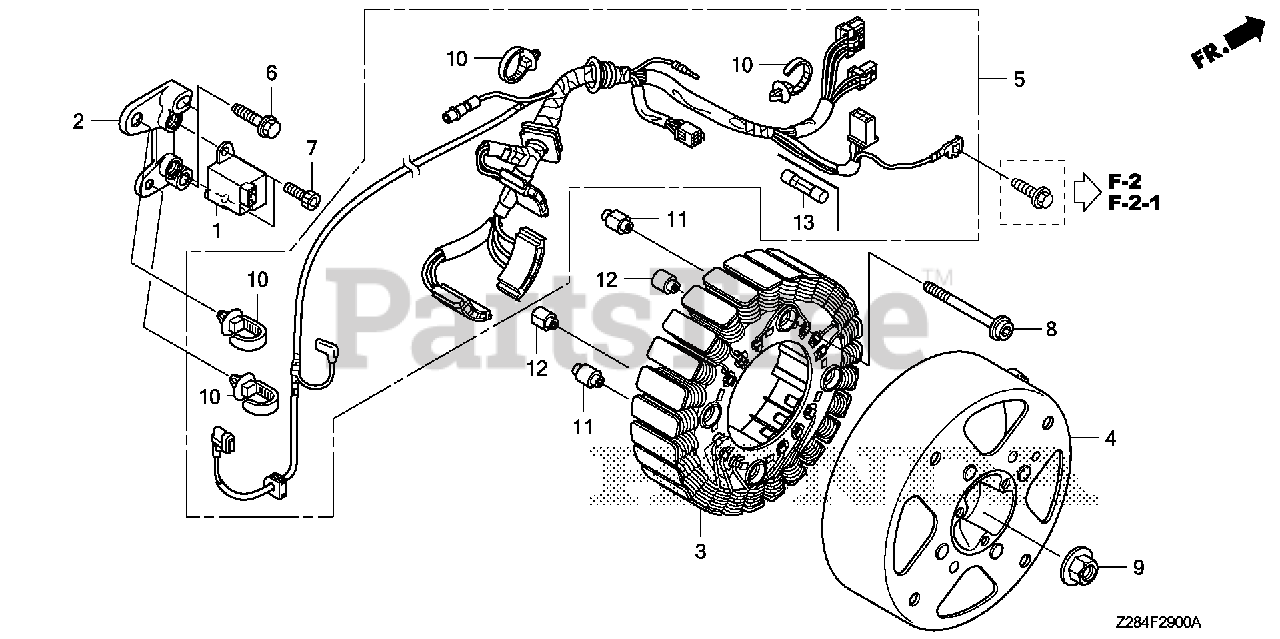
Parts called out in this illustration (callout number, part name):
1	GENERATOR ASSY., PULSE (TEC)
2	BRACKET, PULSER COIL
3	COIL SET, INSULATED VARNISH
5	WIRE HARNESS ASSY., GENERATOR
6	BOLT, FLANGE (6X23)
7	BOLT, SOCKET (5X14)
8	BOLT, FLANGE SOCKET (6X57) (CT200)
9	NUT, SPECIAL (14MM)
10	CLIP, HARNESS BAND (145MM) (BLACK)
11	COLLAR, STATOR
12	COLLAR, STATOR
